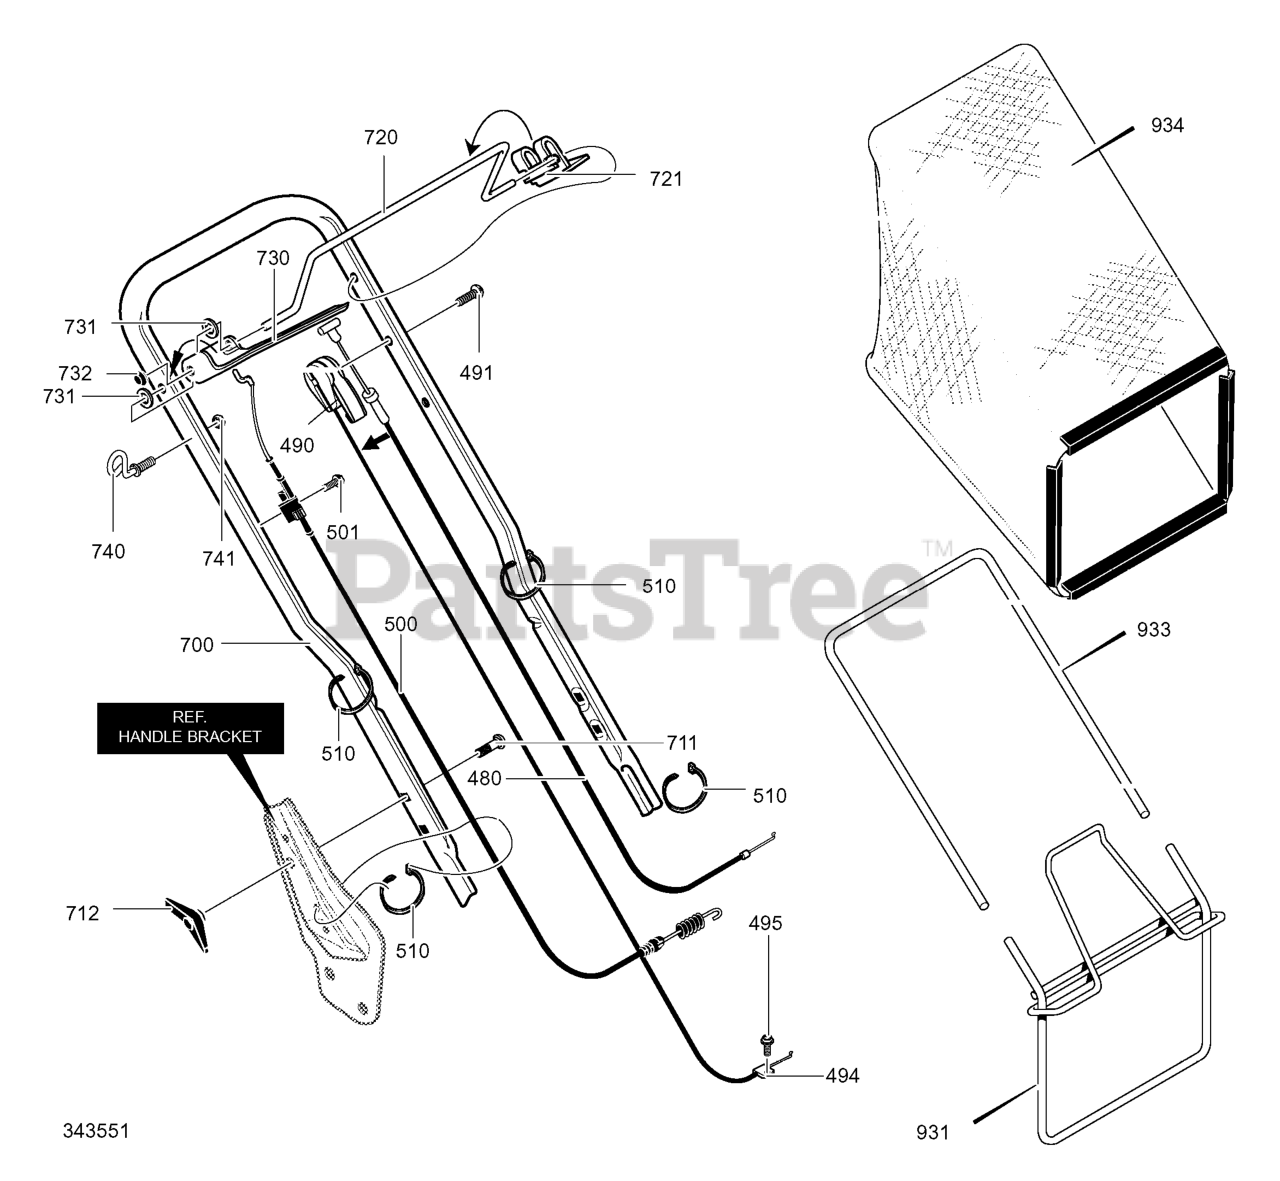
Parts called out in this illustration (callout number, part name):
480	Cable, Stop
490	T-Cable
491	Screw 1/4-20x2.00
494	Clamp, Throttle
495	Screw, 10-32x.62
500	Drive Cable
501	Screw, 10-16x.75
510	Cable Tie
711	Bolt, Carriage 5/16-18x2
712	Knob, Wing
720	Lever, Stop Engine
721	Bracket, Stop Lever
730	Lever, Drive Control
731	Washer, Nylon
732	Cap, Push On
740	Rope Guide
741	Nut, 1/4-20 Hexnyl
931	Bag, Frame Assy.
933	Frame, Catcher Bag
934	Bag, Catcher
